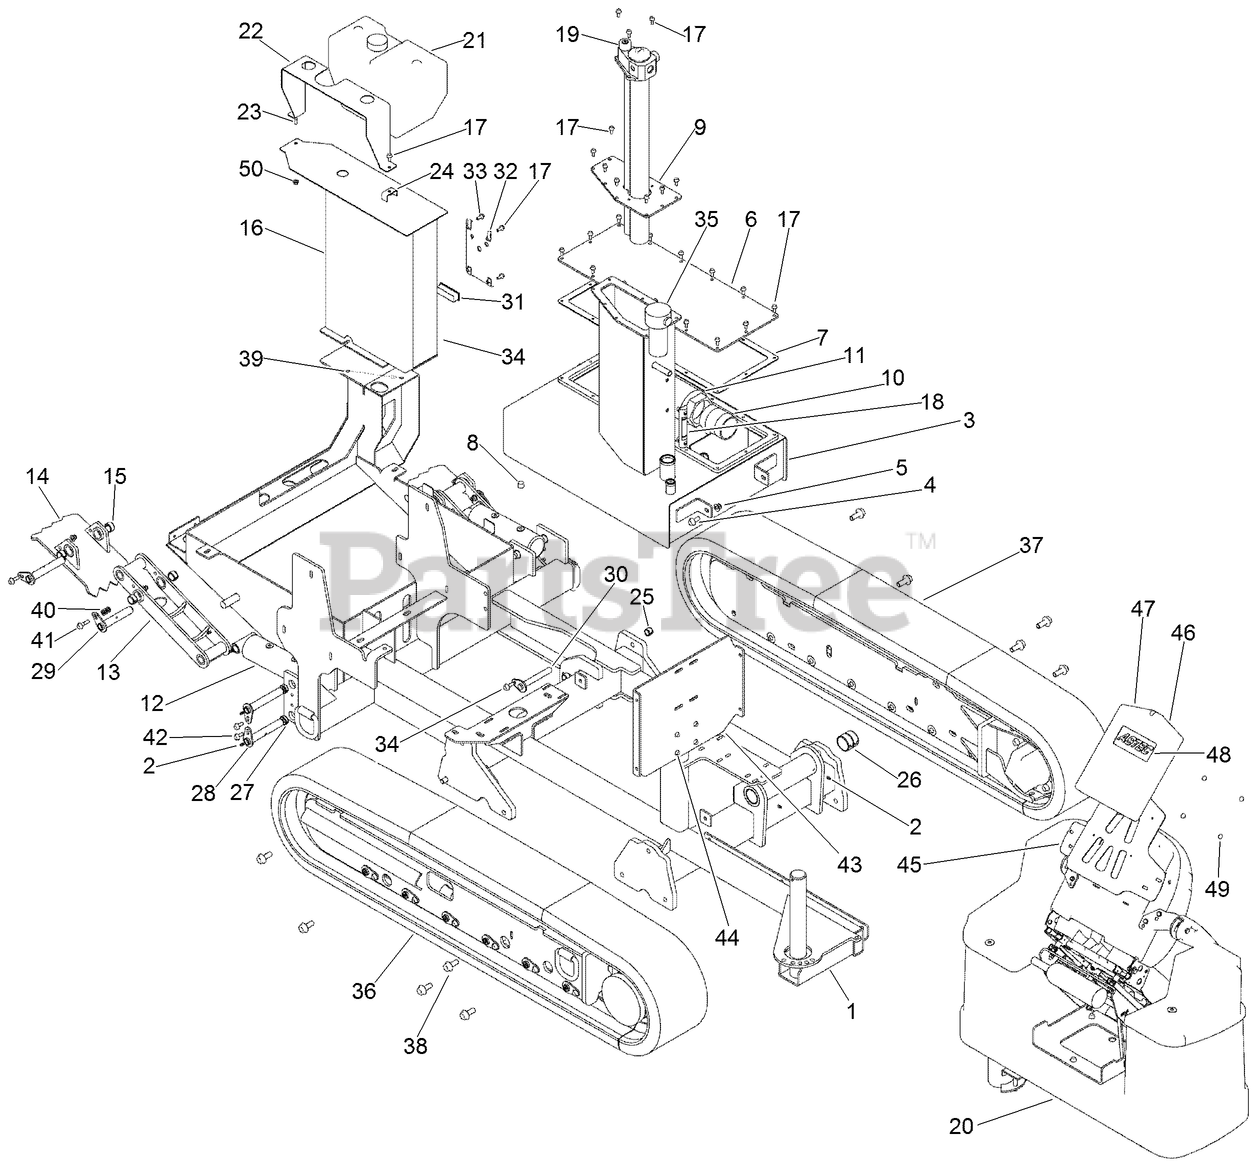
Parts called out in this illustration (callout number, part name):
1	FRAME - Main
2	FITTING-Lube 1/4-28 Tpr SAE-LT .54 Long
3	TANK - Hydraulic
4	SCREW, METRIC FLANGE w/BODY-M12 x 30
5	NUT-HHF, LOCK
6	PLATE - Hydraulic Tank Cover
7	GASKET-COVER LID, HYDRAULIC TANK
8	PLUG-PIPE, HEX SOCKET
9	PLATE - Hydraulic Tank Lid
10	NIPPLE-PIPE
11	STRAINER-SUCTION, 100 MESH
12	HYD CYLINDER ASM
13	WELDMENT - Stabilizer Leg
14	WELDMENT - Stabilizer Foot
15	BUSHING-SPRING
16	WELDMENT - Rear Controls Box
17	SCREW, METRIC FLANGE w/BODY - M8 x 20
18	GAUGE-SIGHT
19	FILTER ASM (HYDRAULIC TANK)
20	ASSEMBLY - Operators Console
21	BOTTLE - Mud Pump System Anti-Freeze
22	BRACKET - Anti-Freeze Bottle
23	SCREW, METRIC FLANGE w/BODY - M8 x 45
24	NUT-TORQUE, PREVAILING
25	BUSHING-SPRING
26	BUSHING-SPRING
27	BUSHING-SPRING
28	PIN-FLAG
29	PIN-FLAG
30	PIN-FLAGGED
31	LATCH-TRIGGER, RAISED (W/LOCK)
33	PLATE - Rear Controls Panel
34	SCREW-HH
35	FILTER-HYD, 350PSI (6 MICRON)
36	ASSEMBLY - Track RH
37	ASSEMBLY - Track LH
38	SCREW-HHF
39	NUT-FLANGE, NYLOCK
40	WASHER - 0.406 x 0.750 x 0.119 in CST ZND
41	SCREW-HHF
42	SCREW-FLANGE
43	PLATE - Fuse Box Mount
44	SCREW-HH
45	PLATE - Operators Manual Case Mounting
46	HOLDER-MANUAL, OPERATOR
47	LANYARD
48	POST-MANUAL
50	NUT, METRIC HEX FLANGE - M8, Zinc
